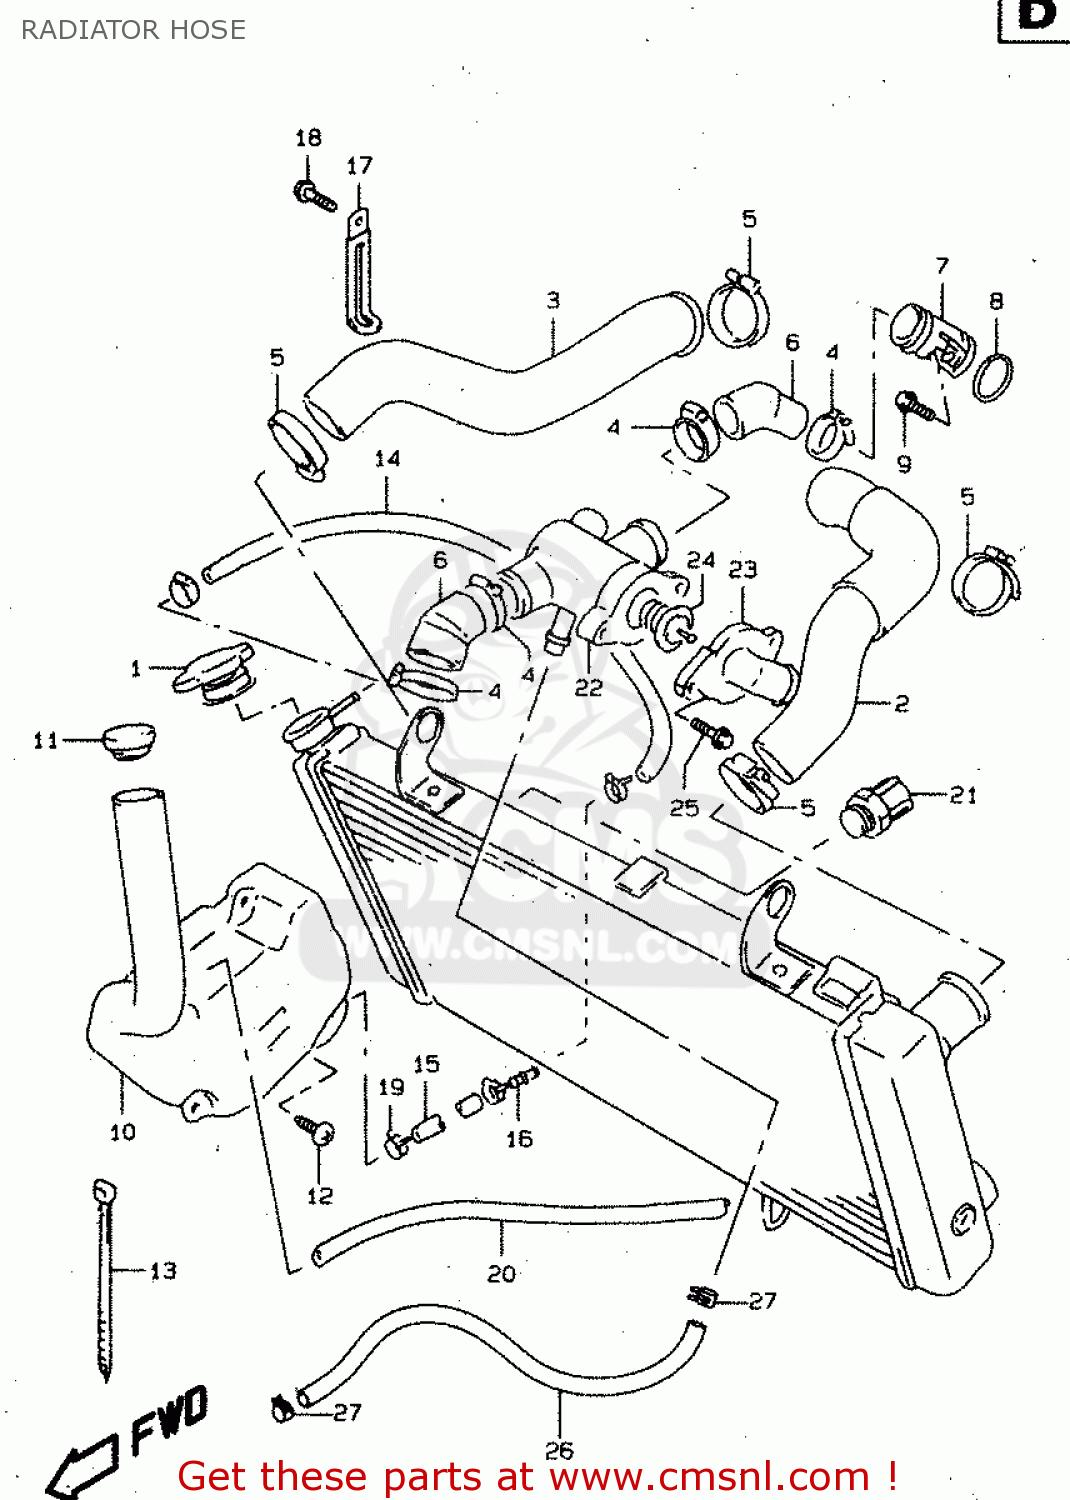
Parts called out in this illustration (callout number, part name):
1	CAP,RADIATOR
2	HOSE,RADIATOR INLET
3	HOSE,RADIATOR OUTLET
4	CLAMP
5	CLAMP
6	HOSE,CONNECTOR INLET
7	UNION,CONNECTOR HOSE
8	O RING(D:3.2,ID:17.8)
9	BOLT
10	TANK ASSY,RESERVOIR
11	CAP,RESERVOIR TANK
12	SCREW(5X16)
13	CLAMP
14	HOSE(5X9X600)
15	HOSE(5X9X600)
16	UNION
17	CLAMP(L:65)
18	SCREW 5X8
19	CLIP
20	HOSE(5X9X600)
21	SWITCH,RADIATOR FAN
22	CONNECTOR,THERMOSTAT,INLET
23	CAP,THERMOSTAT CONNECTOR
24	THERMOSTAT,WATER
25	BOLT
26	HOSE,CONNECTOR TO WATER
27	CLAMP
